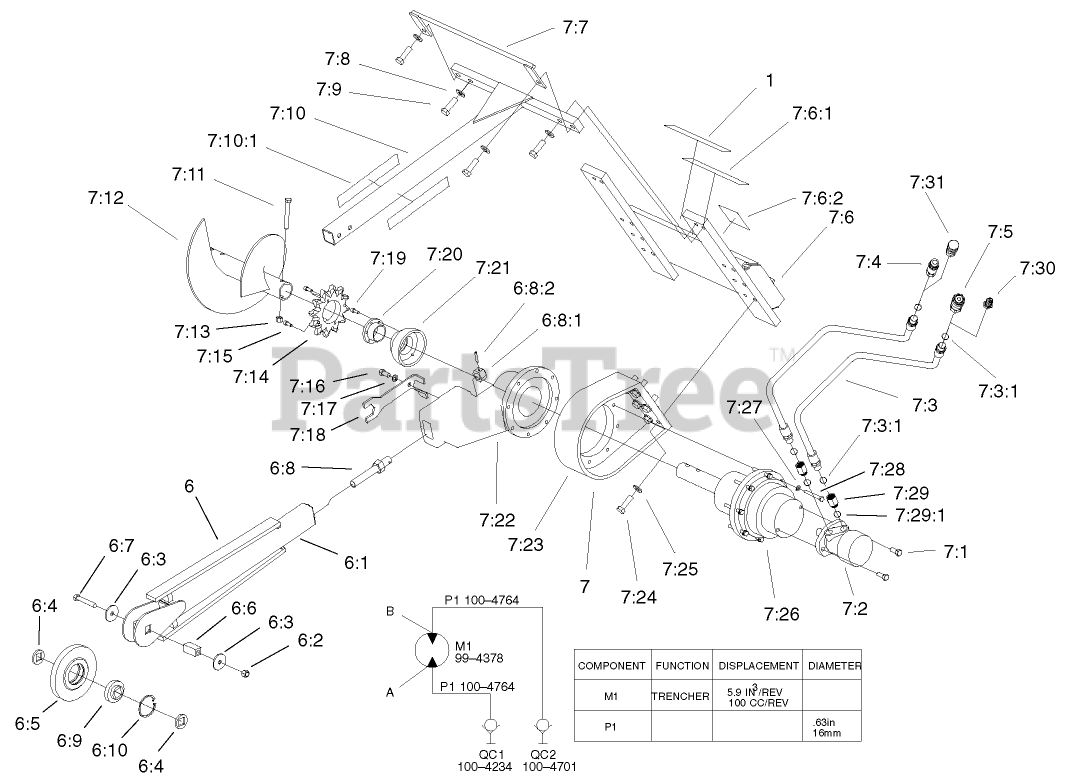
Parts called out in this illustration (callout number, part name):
1	DECAL-ATTACHMENT, DINGO
6	TRENCHER BOOM ASM
6:1	Boom ASM
6:2	NUT-LOCK
6:3	WASHER-ROLLER
6:4	SPACER-ROLLER
6:5	ROLLER-NOSE
6:6	PIN-ROLLER
6:7	SCREW-HH
6:8	ADJ SCREW ASM
6:8:1	NUT-HEX
6:8:2	PIN-ROLL
6:9	BEARING
6:10	RING-INT
7	Trencher Head ASM
7:1	SCREW-HH, LH
7:2	MOTOR-HYD(OPTIONAL), 100CC-1 INCH SHAFT
7:3	HOSE-HYDRAULIC
7:3:1	O-RING
7:4	NIPPLE-CONNECT, PRESSURE
7:5	COUPLER-FACE, FLUSH
7:6	Frame ASM
7:6:1	DECAL-DANGER
7:6:2	DECAL-DANGER
7:7	HOSE GUIDE ASM
7:8	WASHER-FLAT
7:9	SCREW-HH
7:10	SAFETY RAIL ASM
7:10:1	DECAL-DANGER
7:11	SCREW-HH
7:12	AUGER
7:13	NUT-LOCK, NI
7:14	SAND SPROCKET-12T
7:15	SCREW-HSH
7:16	SCREW-HH
7:17	WASHER-LOCK
7:18	SPANNER
7:19	SCREW-HSH
7:20	LOCK-TAPER
7:21	PROTECTOR-SEAL
7:22	MOUNT-BOOM
7:23	MOUNT-DRIVE, PLANETARY
7:24	SCREW-HH
7:25	WASHER-FLAT
7:26	GEARBOX ASM
7:27	WASHER-LOCK
7:28	SCREW-HH
7:29	ADAPTER-CONVERSION
7:29:1	O-RING
7:30	DISCONNECT-QUICK, MALE
7:31	DISCONNECT-QUICK, FEMALE
